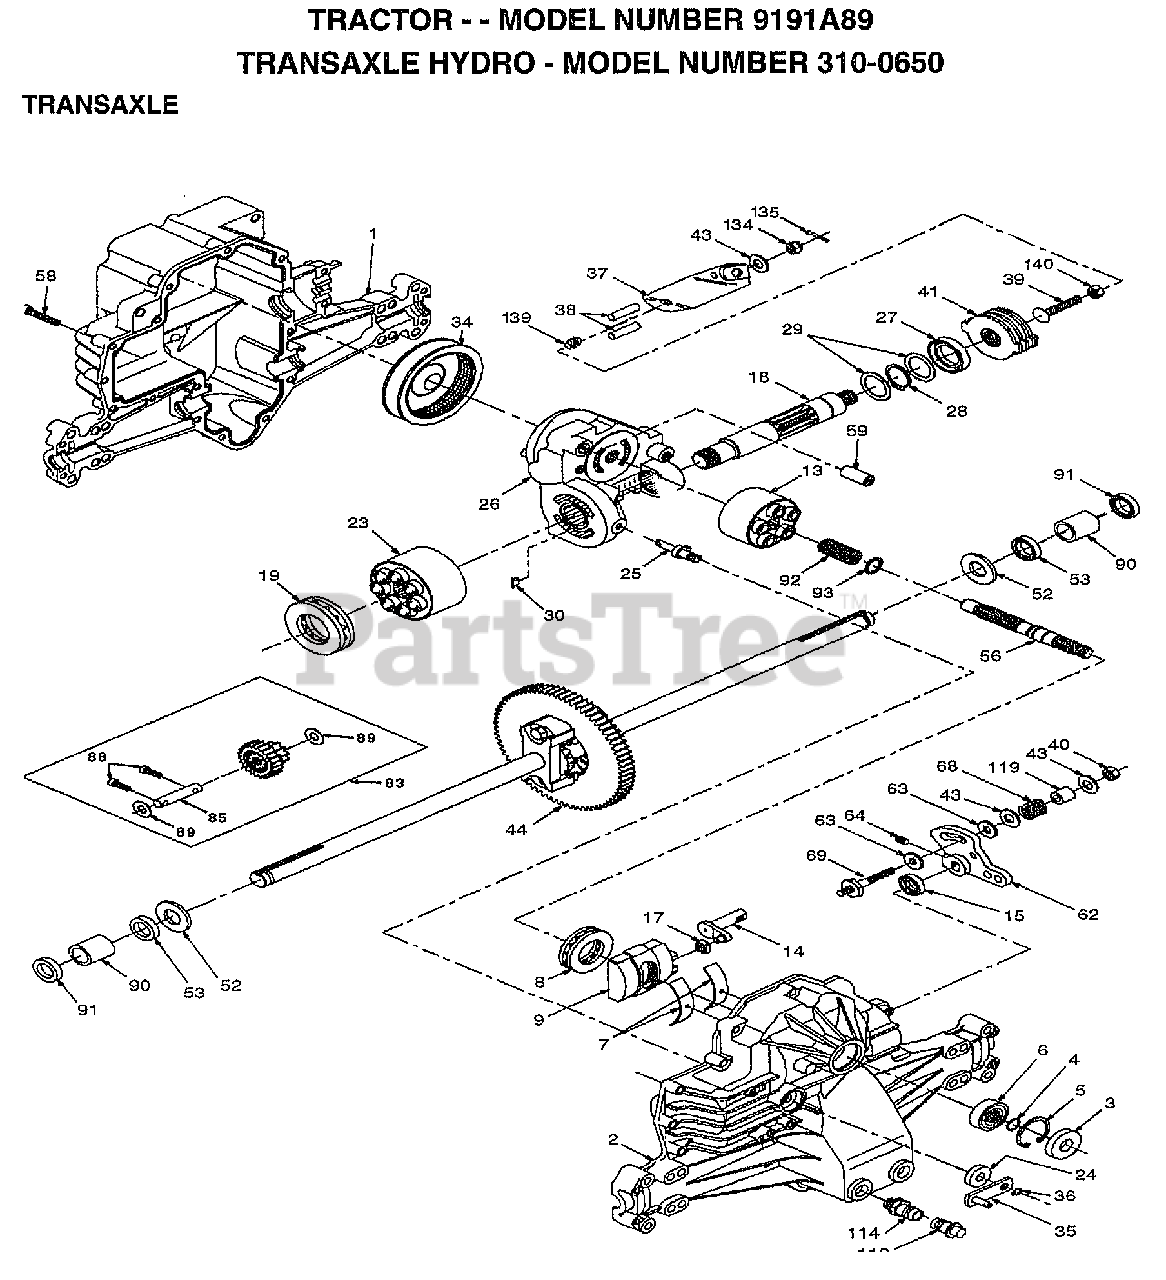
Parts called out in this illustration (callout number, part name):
1	HOUSING.L.50074RM
2	HOUSING.UP.70125
3	SEAL.9008000-0128
4	RING.RET.2003016.
5	RING.RET.2003052.
6	BEARING.(50552)42X68X16
7	CRADLE- 2003023.
8	BEARING.THU.50551
9	SWASHPLT.2003087.
13	BLOCK.CLYN.70079.
14	ARM.TRUN.2003005.
15	SEAL.9008000-0126
17	GUIDE.2000015.
18	SHAFT.MOTOR.50449
19	BEARING.THU.50552
23	BLOCK.CYLIN.70082
24	SEAL.LIP.45074
25	ACTUATOR.2003555
26	KIT.CEN.SEC.70250
27	SEAL.LIP.45075
28	RING RETAIN 50007
29	WASHER.44872
34	ELEMENT.OIL.44964
35	ARM.BYPASS.50270
36	RING.RETAIN.44870
37	ARM.ACTUAT.23710
38	PIN.ACTUAT.44891
39	BOLT.50316
40	NUT.LOCK.HX.50317
41	KIT.BRAKE.70135
43	WASHER HYD 44130
44	DIFFRENTIAL.70226
52	WASHER.HYD.44875
53	SEAL.HYDRO.45076
56	SHAFT.INPUT.50005
58	BOLT.1/4-20.44876
59	PIN.HYDRO.50002
62	ARM.CONTROL.50254
63	PUCK.DAMPER.50281
64	SCREW.SET.50018.
68	SPRING.HYD.50277
69	STUD.5/16-24.DANA
83	JACKSHAFT/PINION GEAR.70132
85	PIN.SHAFT 50559
88	SCREW.CAP.50154.
89	WASHER.HYD.50132
90	BEARING.SLV.50118
91	SEAL.WIPER.50941
92	SPRING.2003014.
93	WASHER.2003017
113	CAP.VENT.70109
114	O-RING.ASM.70110
119	SPACER.HYD.50278
134	NUT.CAS.HYD.44142
135	PIN.COT.HYD.44101
139	SPRING.COMP.50431
140	NUT.HEX.50269
